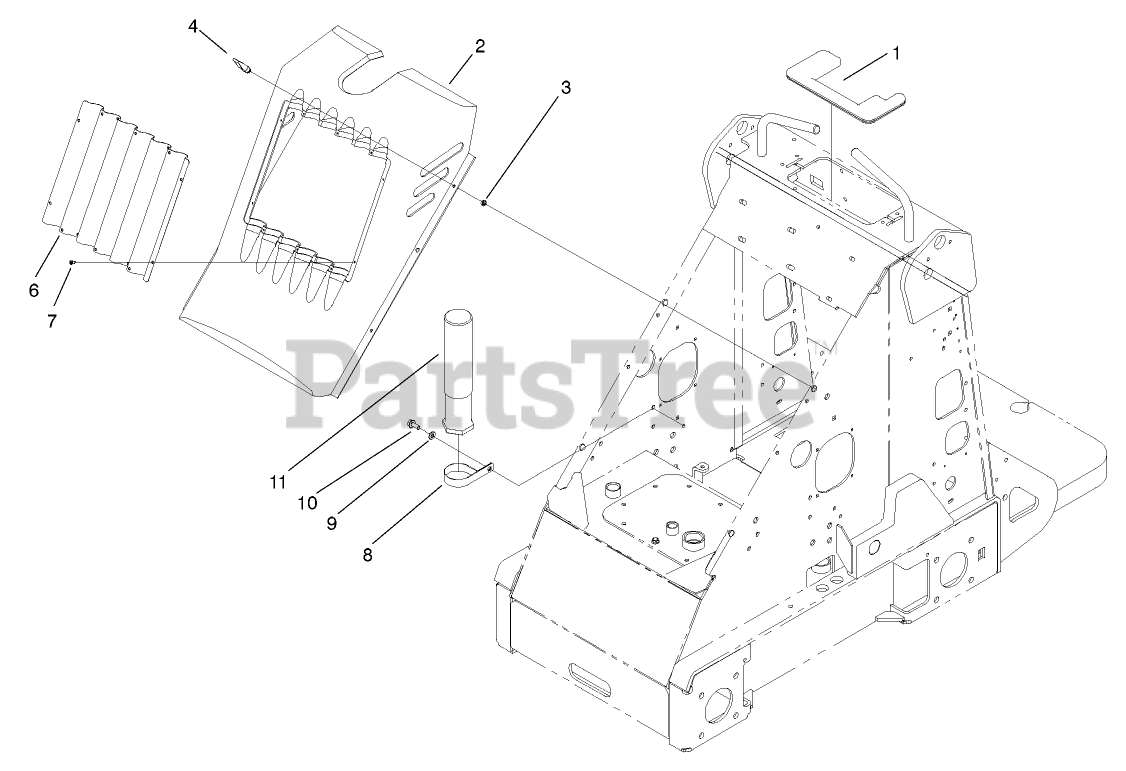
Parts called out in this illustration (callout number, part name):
1	COVER-VALVE
2	COVER-HOOD
3	WASHER
4	LATCH-SWELL
6	GRILLE-SCREEN
7	SCREW-PPH
8	CLAMP-R
9	WASHER-PLAIN
10	SCREW-HWHTF
11	TUBE-MANUAL
